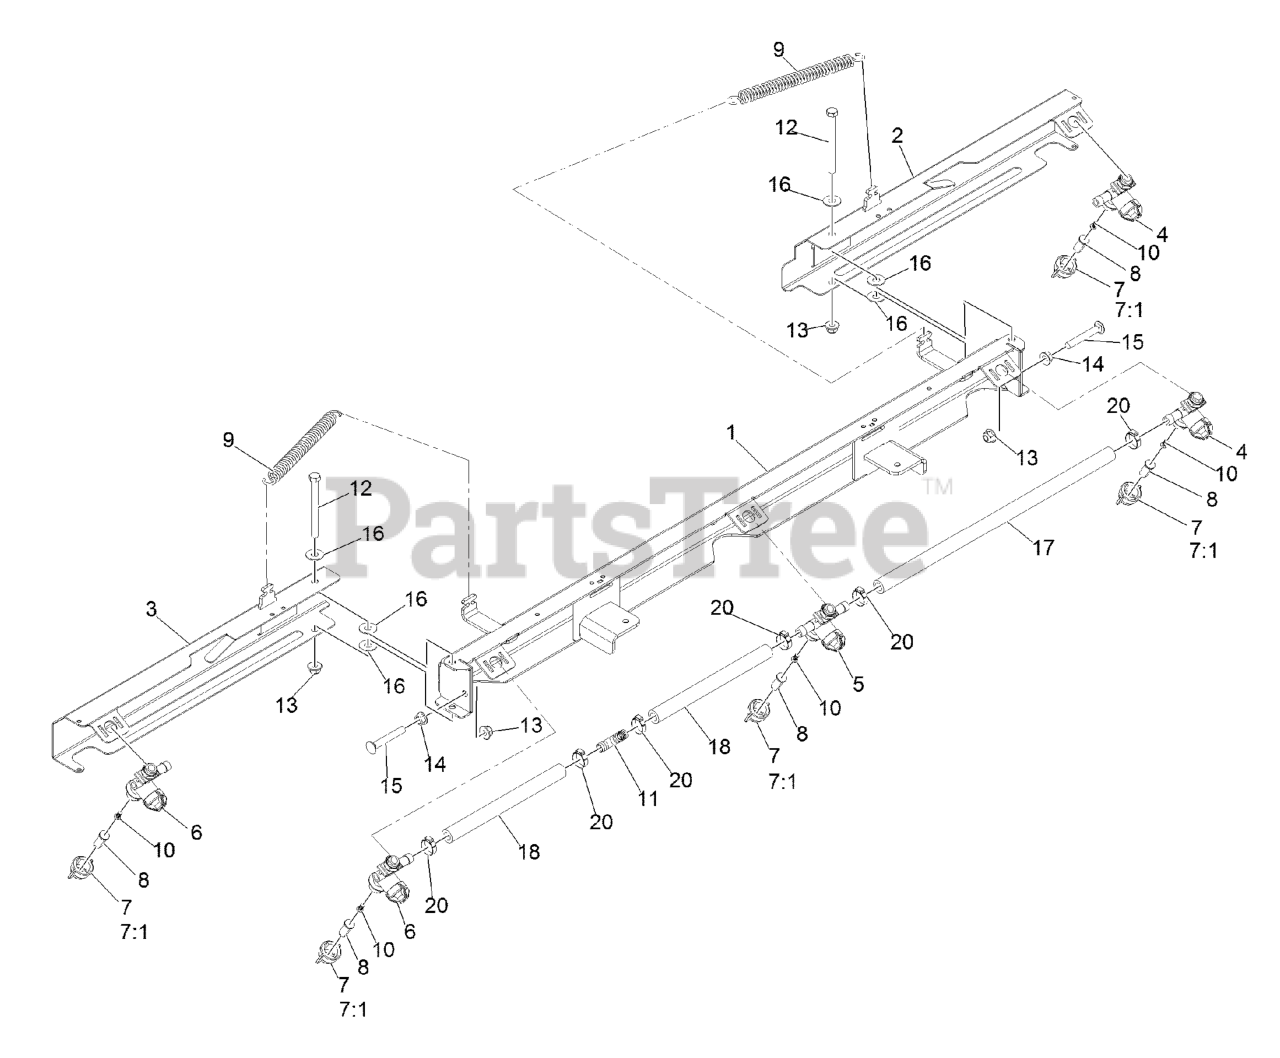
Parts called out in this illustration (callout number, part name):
1	BOOM-CENTER
2	BOOM-WING, RT
3	BOOM-WING, LT
4	BODY-NOZZLE, RIGHT
5	BODY-NOZZLE, CENTER
6	BODY-NOZZLE, LEFT
7	CAP-NOZZLE
7:1	SEAT-GASKET
8	TIP-SPRAY
9	SPRING-EXTENSION
10	STRAINER-NOZZLE, 50M 5PSI
11	FITTING-TEE, BARB
12	SCREW-HH
13	Nut-Hex Flange
14	Nut-Hex Flange
15	SCREW-CARR
16	WASHER-FLAT
17	Hose-Spray
18	Hose-Spray
20	CLAMP-OETIKER, 167
